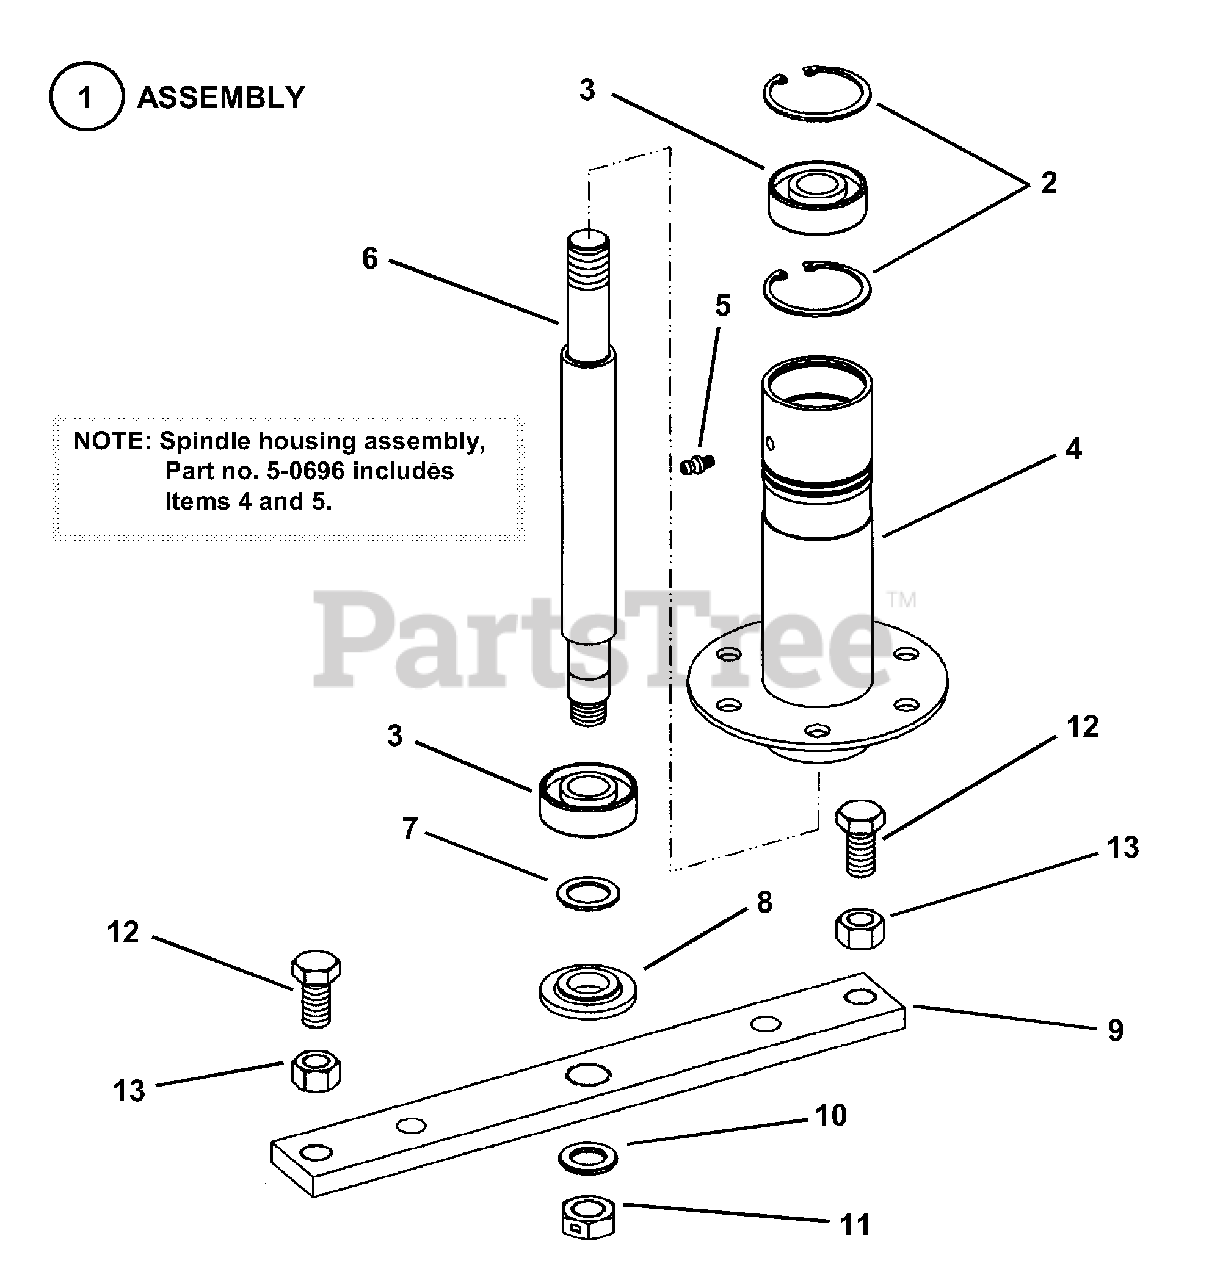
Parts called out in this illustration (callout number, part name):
1	ASSEMBLY, Spindle Housing
2	RING, 1.85" Internal Retaining
3	BEARING, Spindle
4	WELDMENT, Spindle Housing
5	FITTING, Lube (Press fit for .187 hole-no ball)
6	SPINDLE, Shaft (10.237" Long)
7	WASHER, 3/4" Shim
8	WASHER, Spindle
9	HOLDER, Blade
10	SPACER, Blade Centering
11	NUT, 5/8-18 Hex Center Lock
12	SCREW, 1/2-20 x 1-1/4" Hex Head Cap, Grade 5
13	NUT, 1/2-20 Hex Jam
